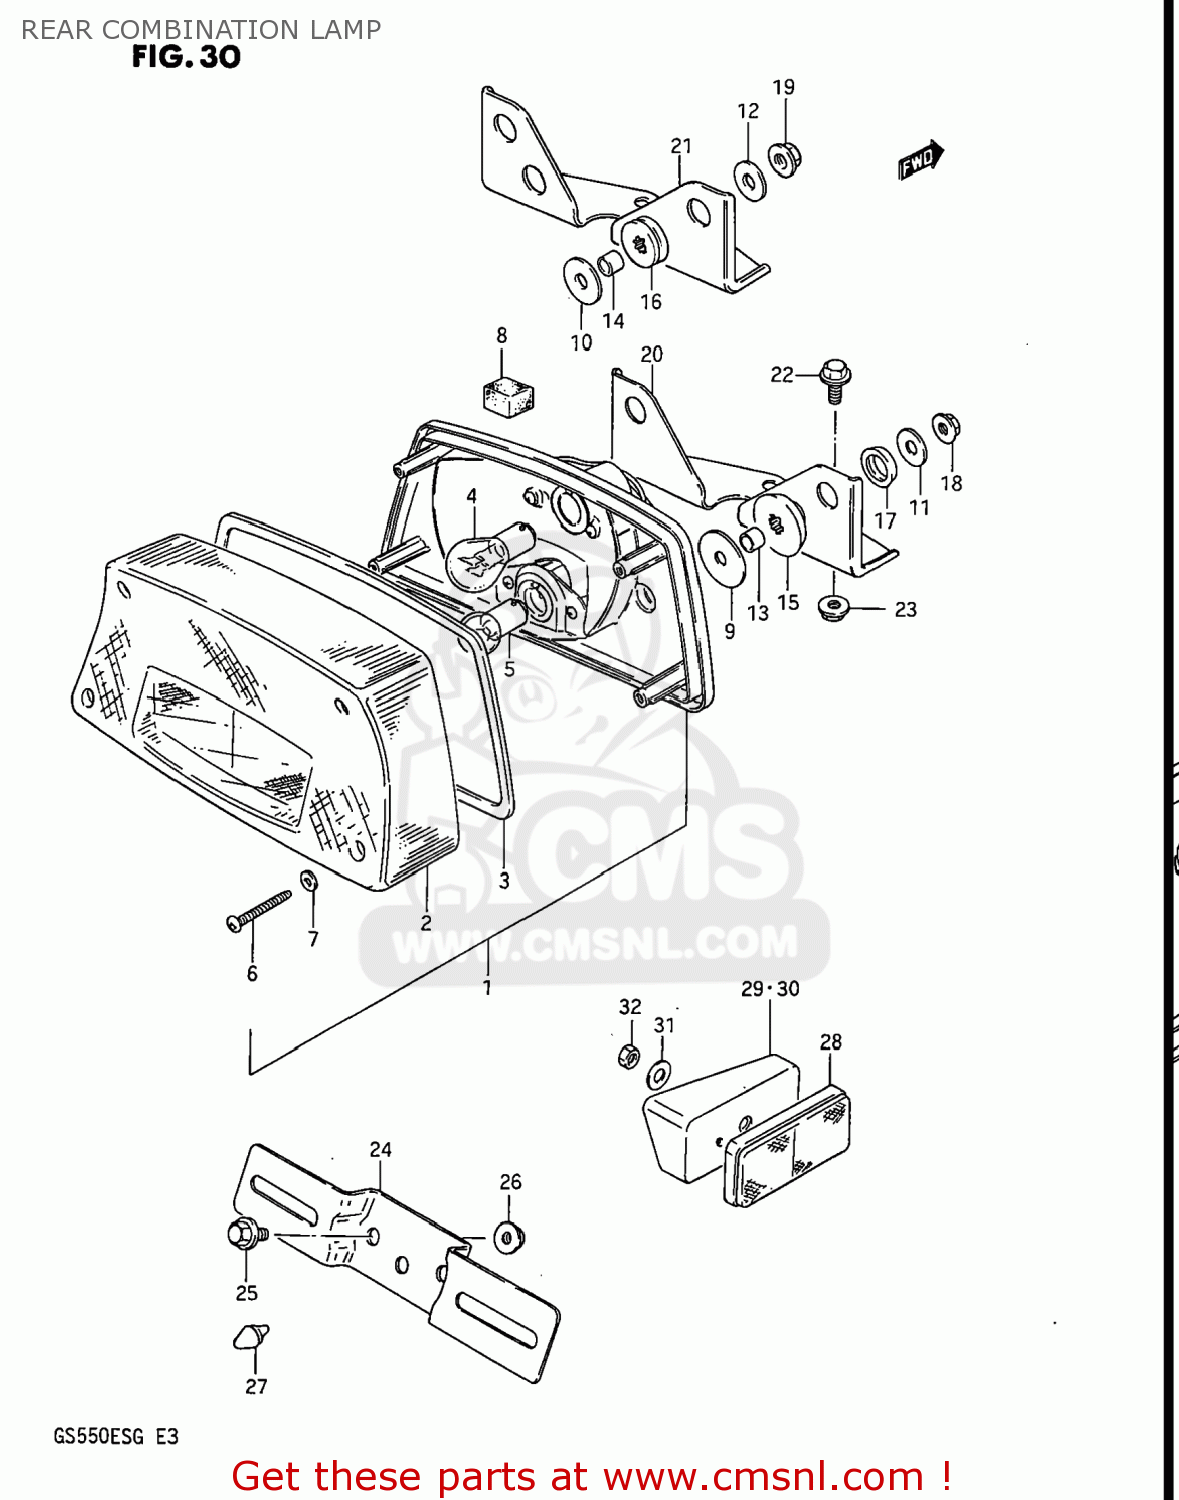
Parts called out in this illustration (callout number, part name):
1	LAMP ASSEMBLY,REAR COMBINATION
2	LENS
3	GASKET
4	BULB(12V23/8W,TOKAI DENSO)
5	BULB
6	SCREW ,4X25
7	GASKET (NAS)
8	CUSHION,REAR COMBINATION LAMP
9	WASHER(6.5X30X1.2)
10	WASHER
11	WASHER(6,5X22X1.6)
12	WASHER(6,5X22X1.6)
13	SPACER (6.8X10X11.5)
14	SPACER
15	CUSHION
16	CUSHION,RR COMBINATION
17	CUSHION
18	NUT
19	NUT
20	BRACKET,REAR COMBINATION LAMP
21	BRACKET,REAR COMBINATION LAMP
22	BOLT
23	NUT
24	BRACKET,LICENSE PLATE
25	BOLT 6X12
26	NUT
27	CUSHION
28	REFLECTOR,REFLEX
29	SPACER,REAR REFLECTOR,RIGHT
30	SPACER,REAR REFLECTOR,LEFT
31	WASHER(5.2X16X1)
32	NUT
